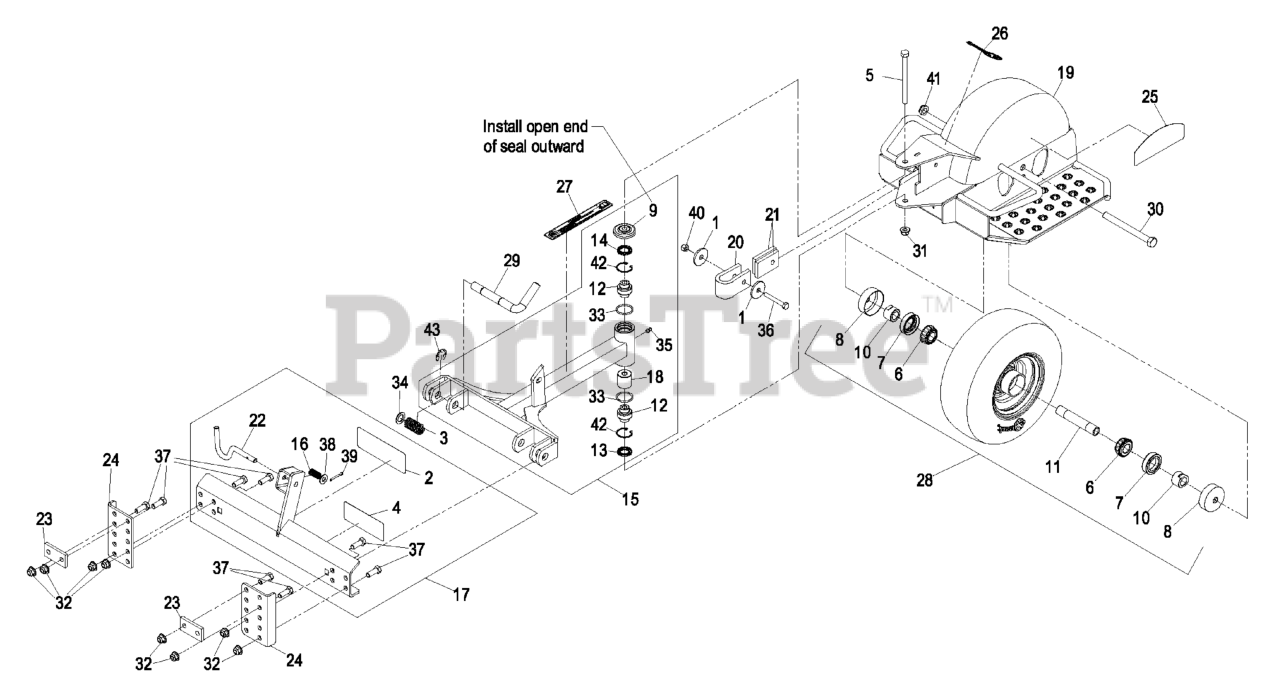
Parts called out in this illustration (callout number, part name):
2	DECAL,BELT DRIVE
3	SPRING,HITCH RELEASE
4	DECAL,SULKY WARNING
5	SCREW-HH
6	BEARING-CONE, TAPERED ROLLER
7	SEAL-CASTER
8	GUARD-SEAL
9	GUARD-TOP
10	SPACER-NUT
12	BEARING-SPHERICAL
13	SEAL-LIP, DOUBLE
14	SEAL-LIP, SINGLE
15	ASM,PULL ARM W/BRGS-DECAL
16	SPRING,LOCK PIN
17	ASM,PULL FRAME
18	SPACER,BALL PIVOT
19	ASM,SULKY FRAME W/DECALS
21	PAD,STOP
22	PIN LATCH
23	PLATE,BACK-UP (PLATED)
24	PLATE,ADAPTER
25	DECAL,STANDON
26	DECAL,EXMARK
27	DECAL,SULKY
28	ASM,WHEEL AND BEARING
29	PIN,PULL ARM (PLATED)
30	SCREW-HH
31	NUT-LOCK, NI
32	NUT-HF, NI
34	WASHER-FLAT
35	FITTING-GREASE
36	SCREW-HH
37	SCREW-HH
38	WASHER-FLAT
39	PIN-COTTER
40	NUT-LOCK, NI
41	NUT-HEX
42	RING-SNAP
